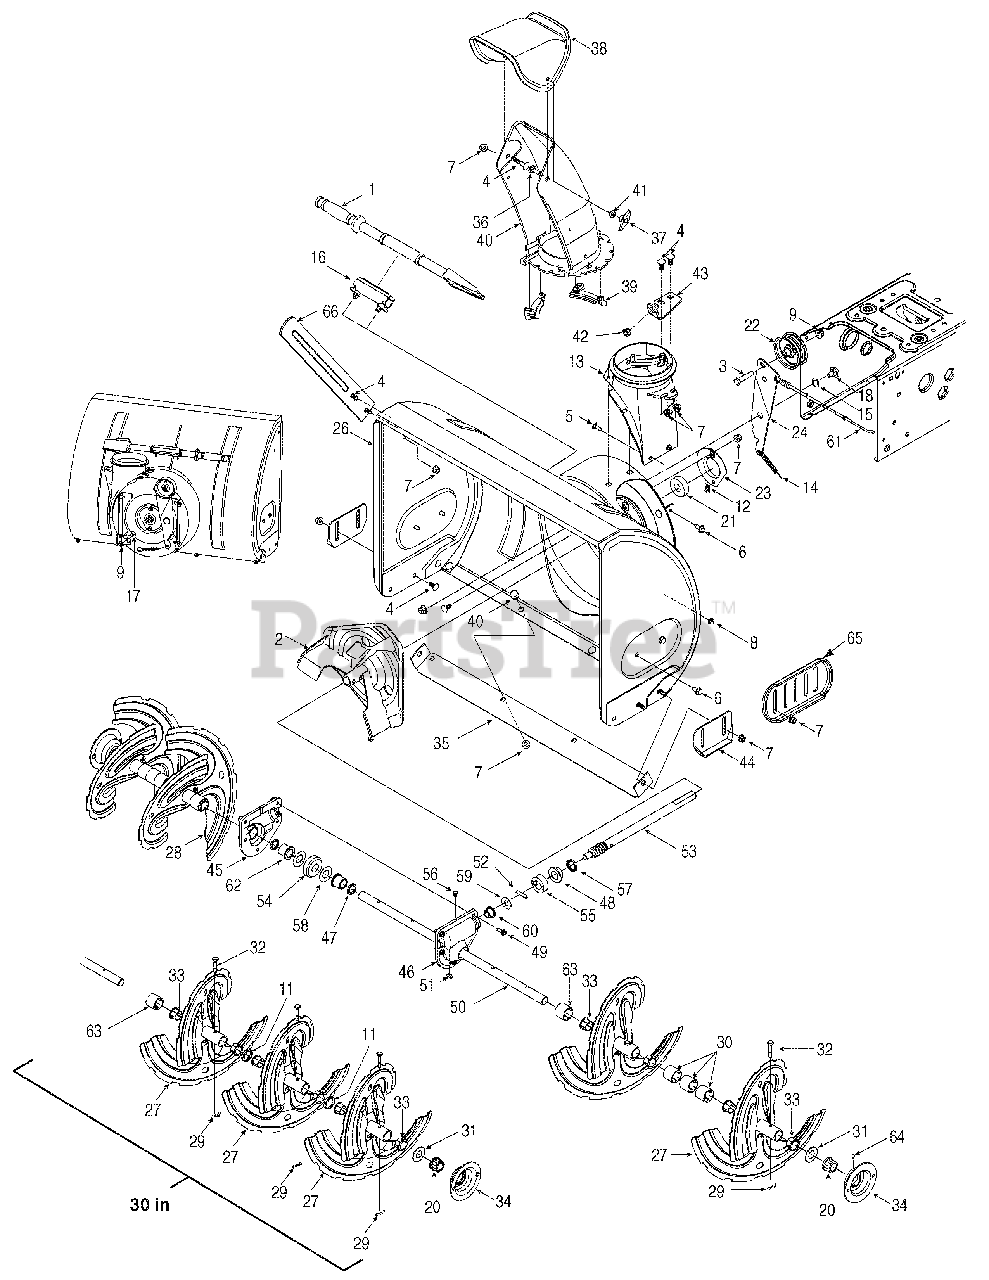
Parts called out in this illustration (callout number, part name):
1	Clean-Out Tool
3	Hex Screw 3/8-16 x 1.75
4	Carriage Bolt 5/16-18 x .75 Gr. 1
5	Carriage Screw 1/4-20 x .75 Gr. 5
6	Hex Wash HD AB Tap Scr 5/16-18 x .625
7	Flange Locknut 5/16-18 Gr. F Nylon
8	Hex L-Flanged Nut 1/4-20 Gr. F Nylon
9	Hex L-Flanged Nut 3/8-16 Gr. F Nylon
11	Spacer 1.25 x .75 x 3/16" Lg.
12	Push-on Nut .25 dia.
13	Chute Adapter
14	Extension Spring
15	Wave Washer .660 ID x .88 OD x .010
16	Cleanout Tool Mount
17	Shld. Scr. .500 Dia. x .335" Lg.
18	Shoulder Scr .625 Dia x .170
20	Hex. Flange Brg. .751" I.D.
21	Self-aligning bearing
22	Flat Idler Pulley 2.75" OD
23	Bearing Housing 1.85 ID
29	Bow Tie Cotter Pin
31	Flat Washer .760 ID x 1.49 OD
32	Shear Pin .25 x 1.5 Gr. 2
33	Flange Bushing
36	Carriage Bolt 5/16-18 x 1.0
37	Handle Knob Assembly
38	Upper Chute
39	Chute Flange Keeper
40	Lower Chute
42	Plastic Bushing .380 ID
45	RH Reduced Auger Housing
46	LH Reduced Auger Housing
47	Oil Seal 3/4 ID
48	Flange Bearing .75 ID x 1.00 OD x .50
49	Thd Forming Scr. 1/4-20 x .75
50	Auger Axle
51	Hi Pro Key 3/16 x 5/8
52	Dowel Pin .25 OD x 1.2
53	Worm Shaft .75 OD
54	Worm Gear 20T
55	Thrust Collar
56	Plug, 1/4 x .437
57	Oil Seal .75 x 1 x .131
58	Flat Washer .76 ID x 1.5 OD x .03
59	Fl. Washer .510 x 1.120 x .060
60	Flange Bearing .75 ID x 1.0 OD x .925
61	Auger Clutch Cable (w/"Z" fitting)
62	Flange Bearing.75 ID x 1.0 OD x .975
63	Spacer 1.25 x .75 x 1.00
64	Grease Fitting
67	Cupped Washer .340 x 872 x .060
68	Hex Wash HD AB Tap Scr 5/16-18 x .75
